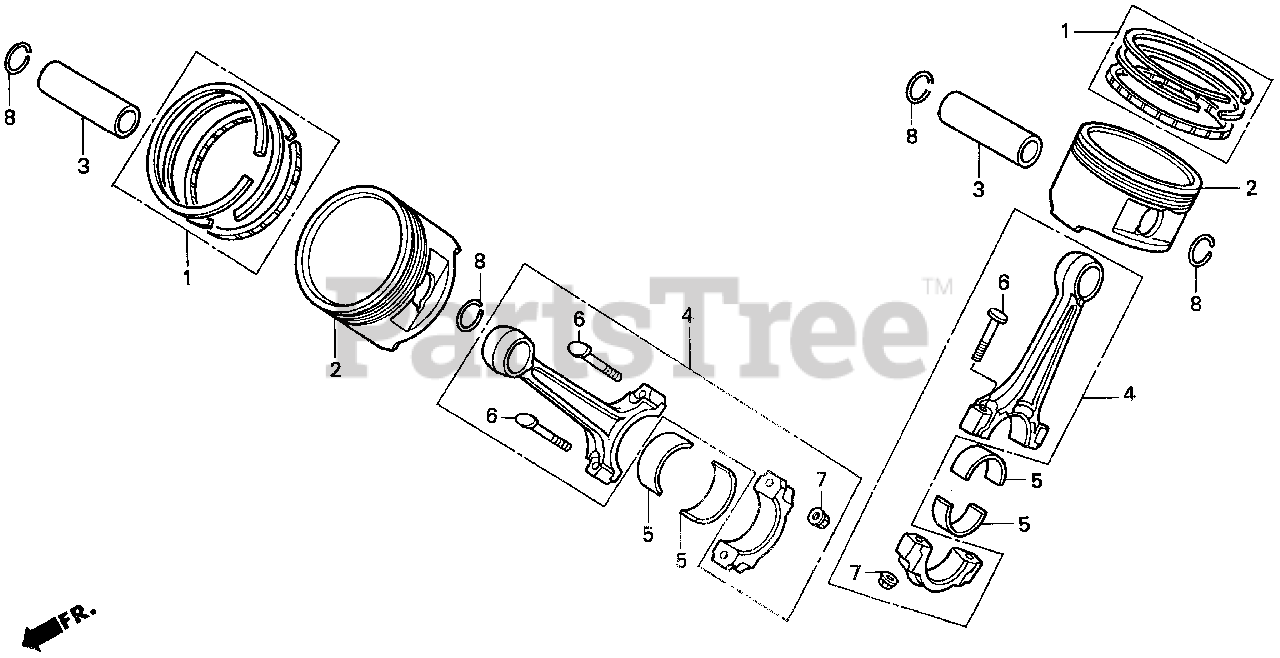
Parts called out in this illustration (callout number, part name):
1	RING SET, PISTON (STD)
1	RING SET, PISTON (OS 0.25)
1	RING SET, PISTON (OS 0.50)
1	RING SET, PISTON (0.75)
2	PISTON
2	PISTON (OS 0.25)
2	PISTON (OS 0.50)
2	PISTON (0.75)
3	PIN, PISTON
4	ROD SET, CONNECTING
5	BEARING A, CONNECTING ROD (BLUE)
5	BEARING B, CONNECTING ROD (BLACK)
5	BEARING C, CONNECTING ROD (BROWN)
5	BEARING D, CONNECTING ROD (GREEN)
5	BEARING E, CONNECTING ROD (YELLOW)
5	BEARING F, CONNECTING ROD (PINK)
5	BEARING G, CONNECTING ROD (RED)
6	BOLT, CONNECTING ROD
7	NUT, CONNECTING ROD
8	CLIP, PISTON PIN (18MM)
